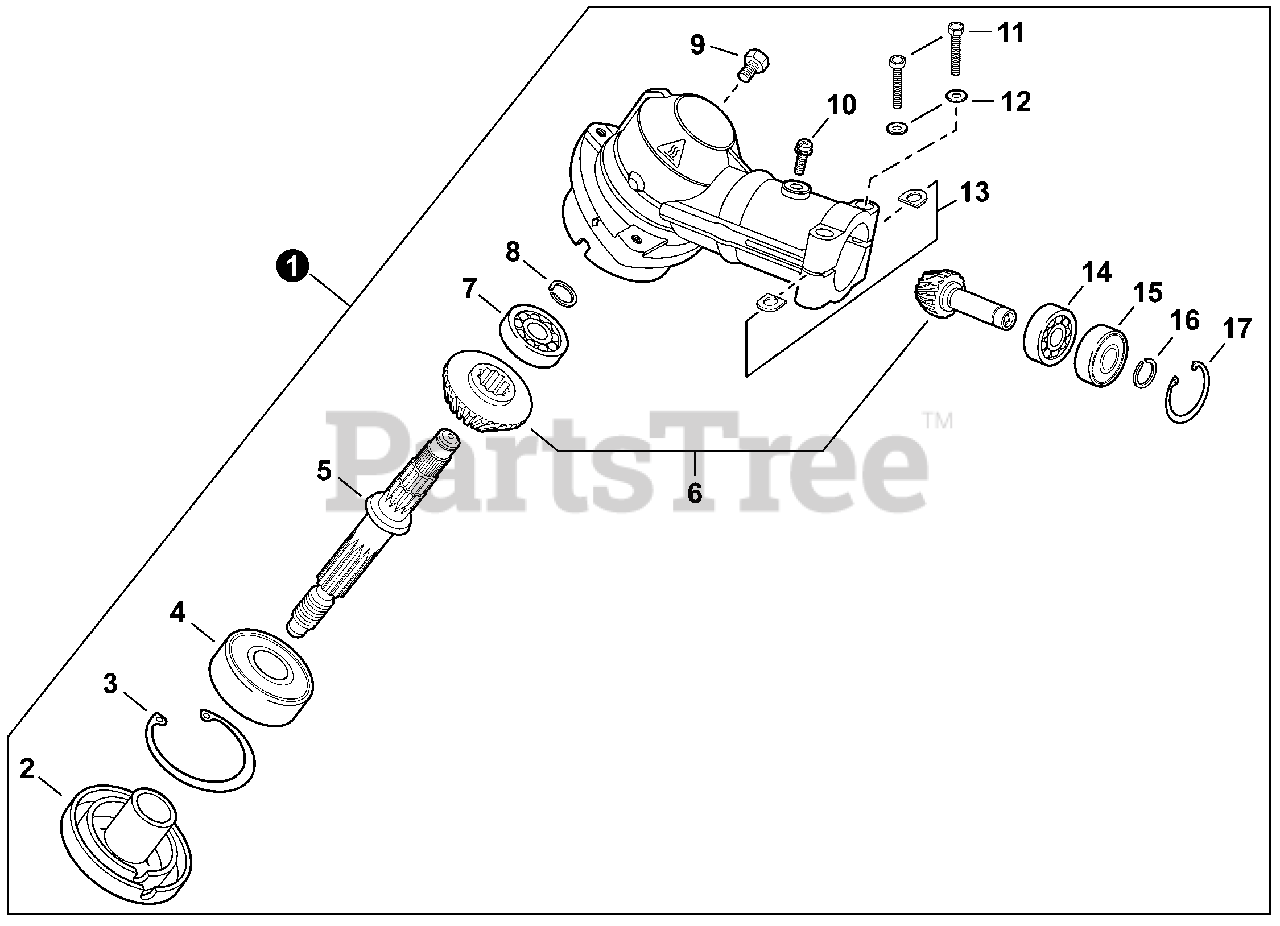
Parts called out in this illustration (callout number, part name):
1	GEAR CASE ASSY
2	PLATE, ADAPTOR - UPPER
3	RING, SNAP Ø42
4	BEARING, BALL 6302
5	SHAFT, GEAR
6	GEAR SET
7	BEARING, BALL 629
8	RING, SNAP Ø12
9	BOLT M8×8
10	SCREW 5×12
11	BOLT 5×35 SP
12	WASHER, FLAT 5.5×10×0.8
14	BEARING, BALL 6900
15	BEARING, BALL 6900Z
16	RING, SNAP Ø10
17	RING, SNAP Ø22
